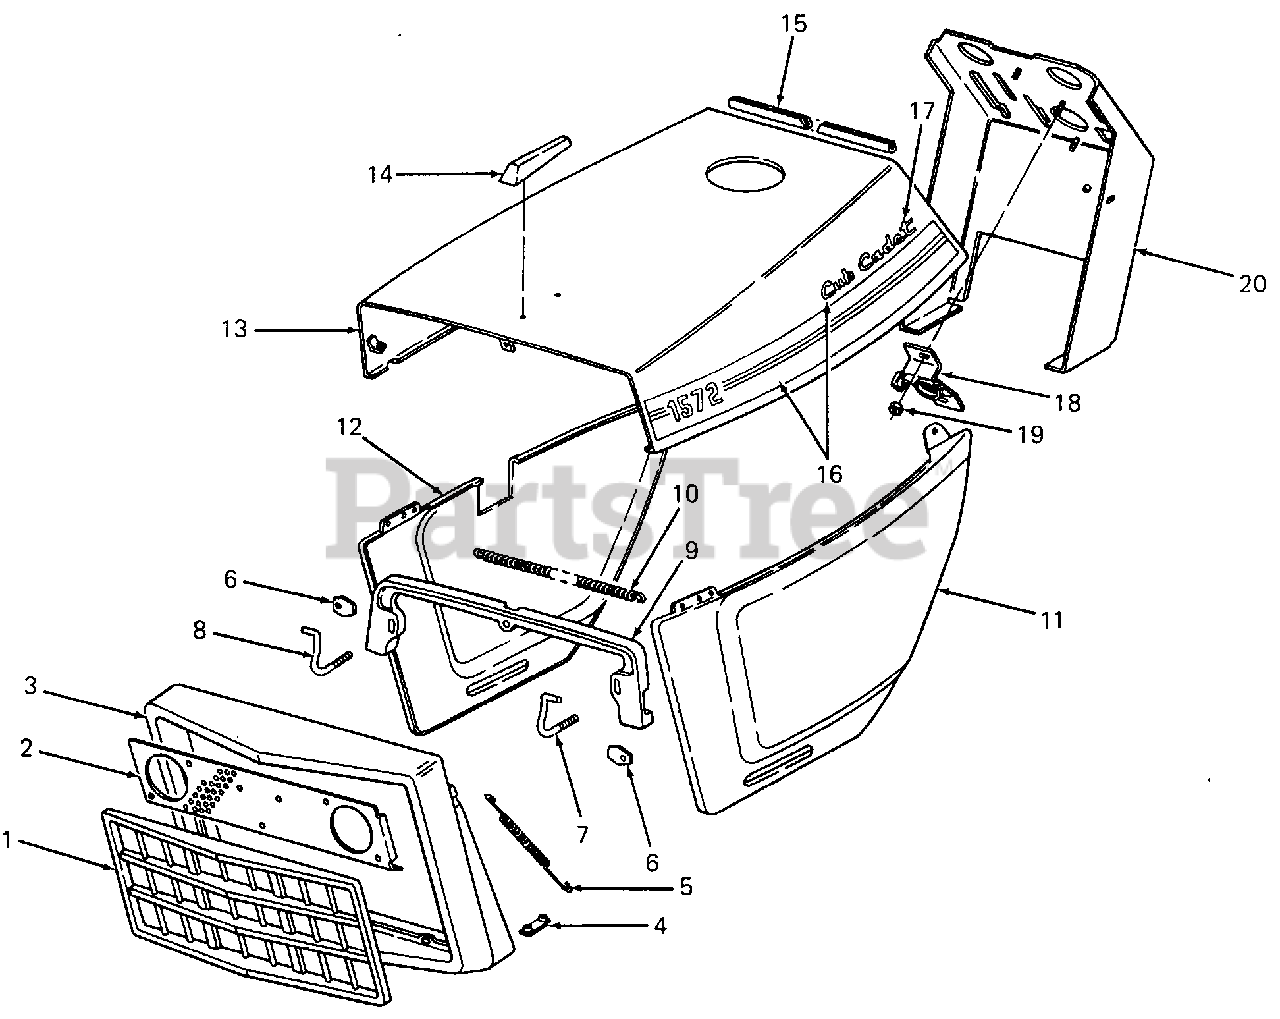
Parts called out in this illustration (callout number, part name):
1	Grille, Insert
4	Retainer, Grille Housing
5	Spring
6	Plate, Hood Hinge
7	Hinge, LH - Hood
8	Hinge, RH - Hood
9	Support, Hood
10	Spring, Side Panel
12	Panel, RH - Side
14	Ornament, Hood
15	Seal, Edge
16	Kit - Hood Label
17	Graphic, Cub Cadet Script w/Adhesive
18	Support, Steering Column
19	Nut, Hex Insert Lock, 1/4-20
